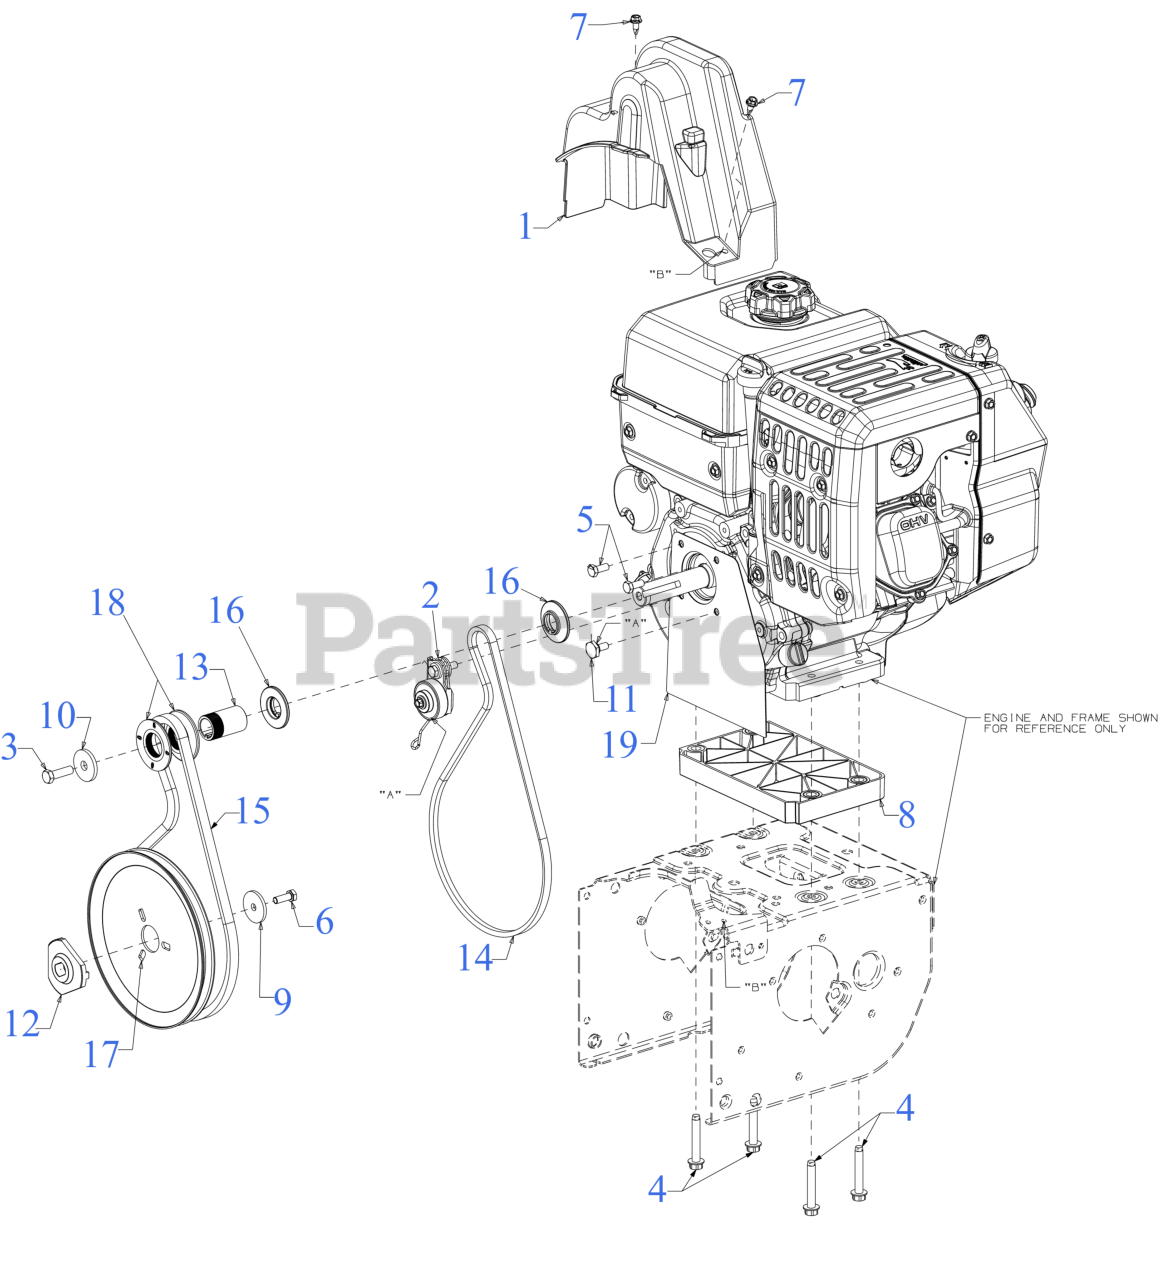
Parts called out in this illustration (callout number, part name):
1	BELT COVER ASSEMBLY
1	HEX SCREW #12-16 x .50
2	IDLER ASSEMBLY
3	SCREW 3/8-24X1.25
4	SCREW 3/8-16 x 2.250
5	SCREW 5/16-24 x .750 GR5
6	SCREW 5/16-24 x .875 GR5
7	SCREW 1/4-20X.625
8	ENGINE MOUNTING SPACER
9	FLAT WASHER
10	FLAT WASHER .45 x 1.5 x .172 HT
11	SHOULDER SCREW
12	ADAPTER PULLEY .75 DIA W/DD
13	PULLEY SPACER
14	DRIVE BELT 3L x 36.90
15	V-BELT .500 x 37.835
16	HALF PULLEY-3/8 V x 1.7160
17	AUGER PULLEY 8.5 OD
18	HALF PULLEY A2.43 x 1.140 SPLINE
19	ENGINE PLATE (FRONT)
